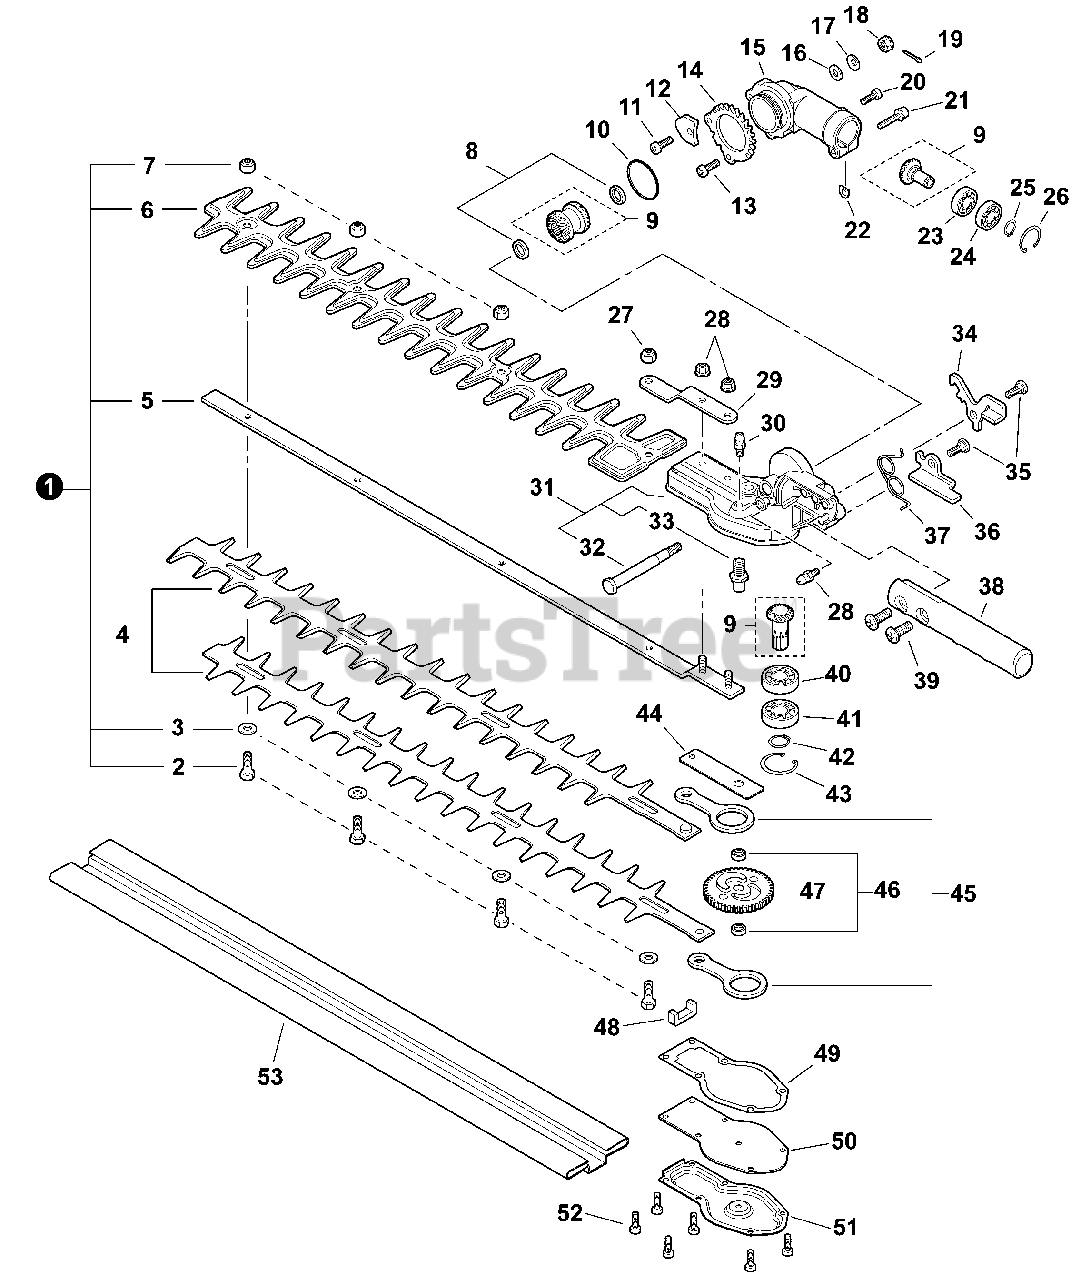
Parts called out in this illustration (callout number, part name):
1	CUTTER ASSY, 22"
2	BOLT M6×20
3	WASHER M6
4	CUTTER 22"
5	GUIDE BAR 22"
6	GUARD, CUTTER BLADE
8	COLLAR Ø16ר10×L= 2
9	GEAR SET
11	SCREW M5×16
12	PLATE, STOPPER
13	BOLT 5×12
14	RING, LOCKING
15	HOUSING, UPPER GEAR CASE
16	WASHER 6.5×13×1
17	WASHER, CONE M6
19	PIN, COTTER Ø1.6×15
20	BOLT 5×12
21	BOLT M5×25
22	D-WASHER
23	BEARING, BALL 609
24	BEARING, BALL 609ZZ
25	RING, SNAP Ø9
26	RING, SNAP 24
28	NUT, FLANGE M5
29	BRACKET, CUTTER
30	FITTING, GREASE
31	GEAR CASE HOUSING ASSY
33	MAINSHAFT
34	LEVER, LOCK
35	BOLT M6
36	RELEASE, LOCK
37	SPRING, TORSION
38	LEVER, ADJUSTMENT
39	SCREW, TRUSS M6×20
40	BEARING, BALL 6001
41	BEARING, BALL 6001ZZ
42	RING, SNAP Ø12
43	RING, SNAP 28
44	PLATE, GUIDE
46	SPACER Ø11ר8×3.4
47	GEAR, CAM
48	PACKING, FELT
49	GASKET, GEAR CASE
51	COVER, GEAR CASE
52	BOLT 4×10
53	SCABBARD
